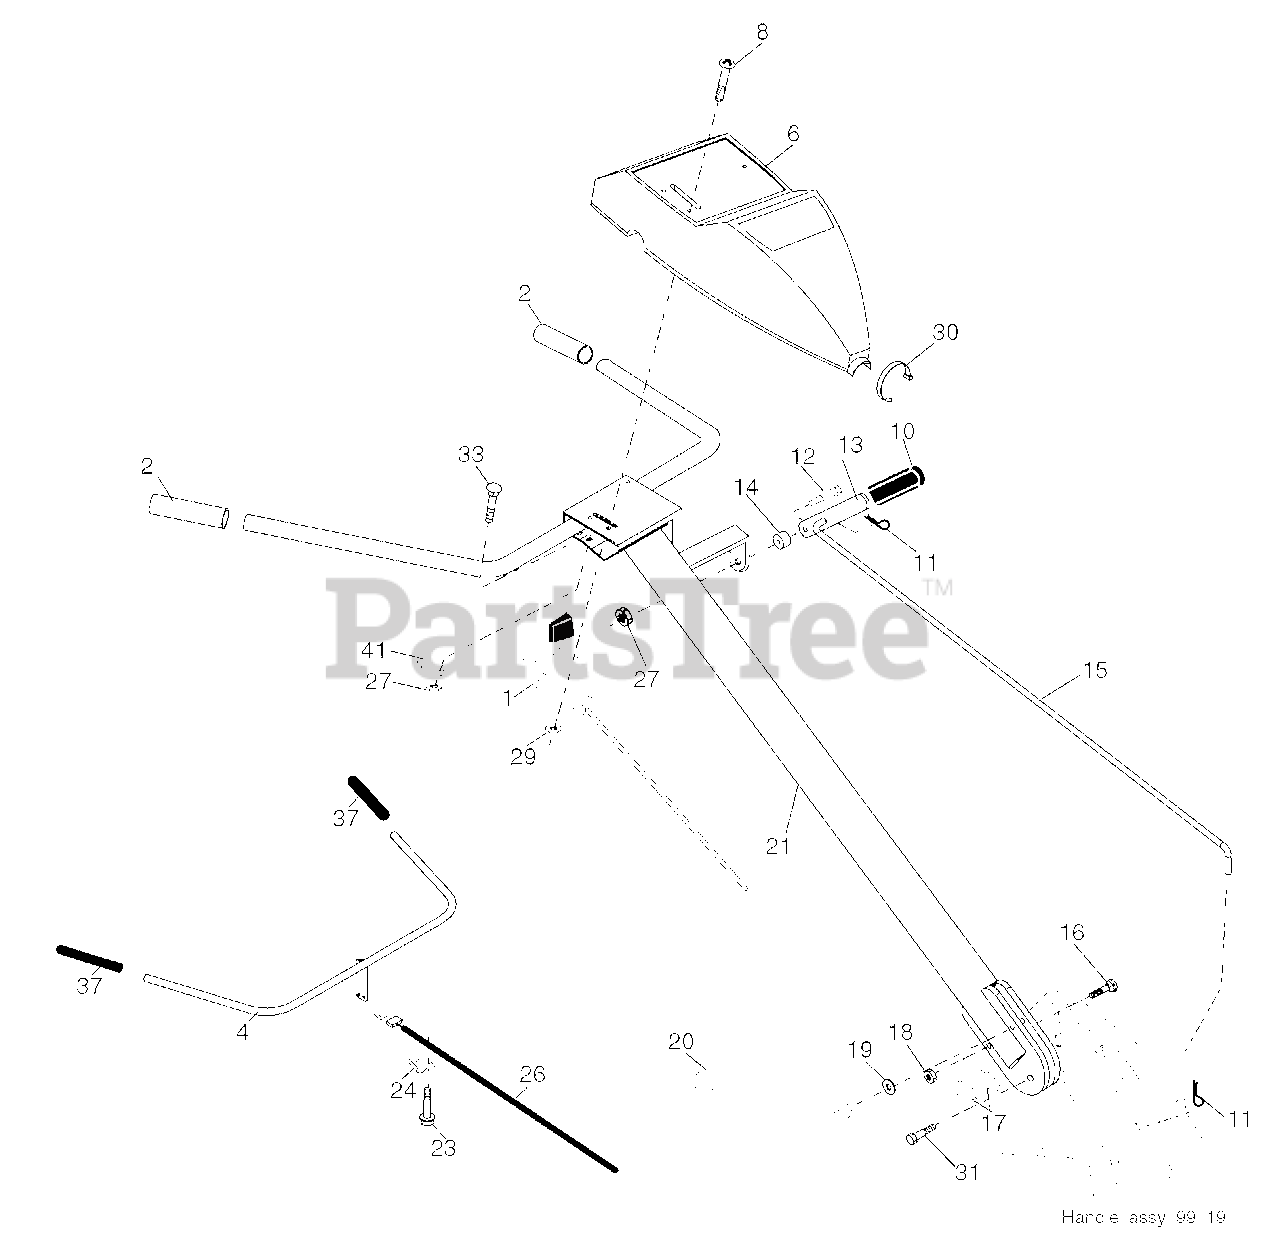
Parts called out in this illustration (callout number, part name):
1	Control, Throttle
2	Grip, Handle
4	Bar Assembly, Control
6	Panel, Control
8	Screw, Phd. #10-24
10	Grip, Handle
11	Clip, Hairpin
12	Bolt, Shoulder
13	Handle, Shift
14	Grommet, Rubber
15	Rod, Shift
16	Bolt, Carriage 3/8-16 x 1 Gr. 5
17	Lock, Handle
18	Nut, Crownlock 3/8-16 unc
19	Washer 13/32 x 1 x 11 Ga.
20	Lever, Lock, Handle
23	Screw, Hex Washer Hd. Slotted #10-24 x 1/2
24	Clip
26	Cable, Clutch
27	Nut Hex Flange 1/4-20 unc
29	Nut, Keps #10-24 unc
30	Tie, Cable
31	Bolt, Pivot
33	Bolt, Carriage 1/4-20 unc x 1/2
37	Grip, Bar, Control
41	Clamp, Bar, Control
